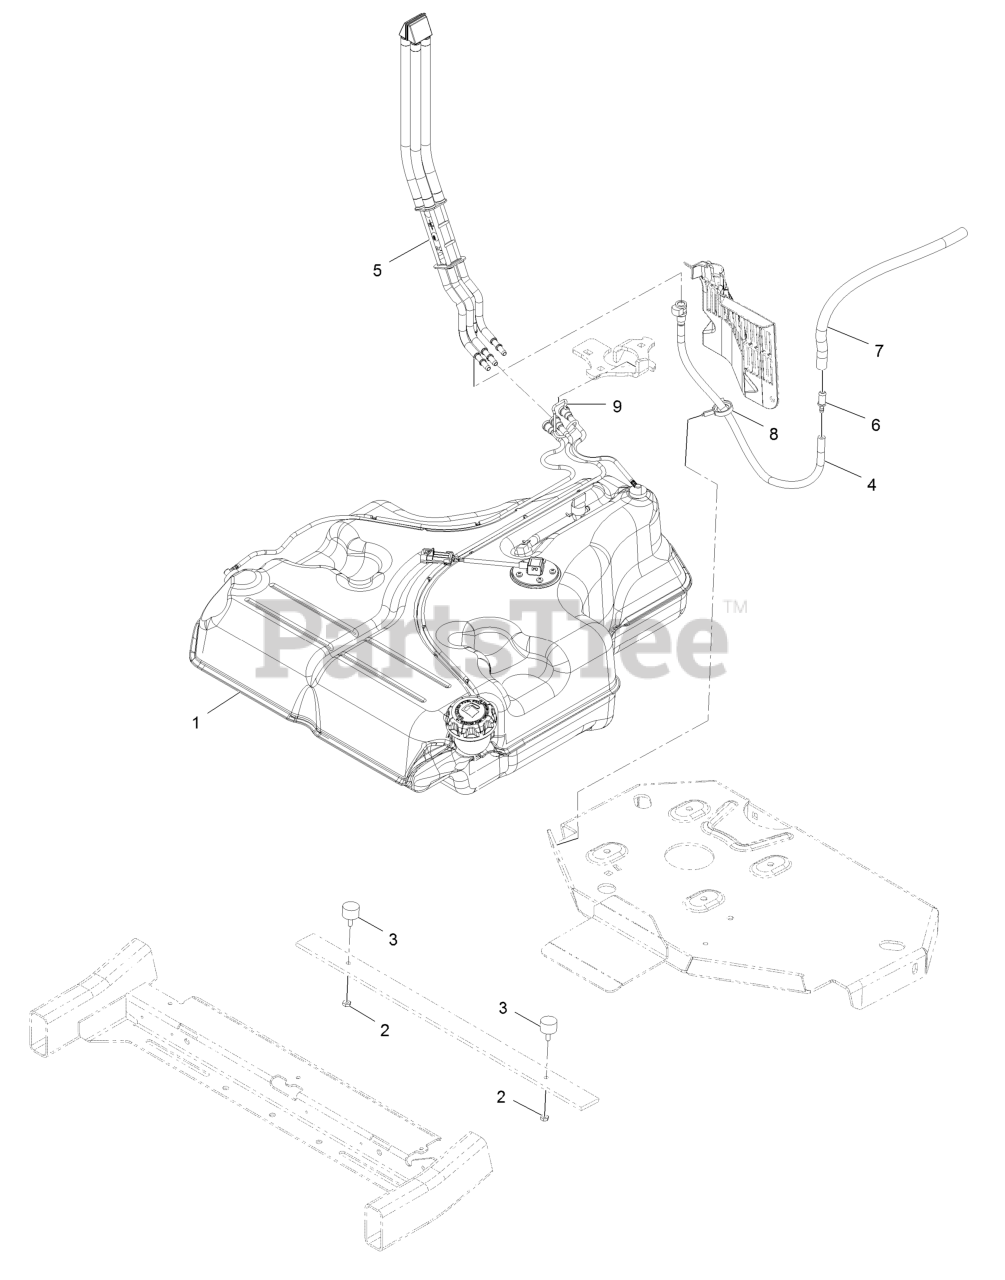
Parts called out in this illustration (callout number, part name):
2	NUT-JAM
4	HOSE ASM
5	FUEL MANIFOLD VENT ASM
6	FITTING-STRAIGHT
7	HOSE-FUEL
8	CLAMP-HOSE
9	RETAINER-LINE, VAPOR
